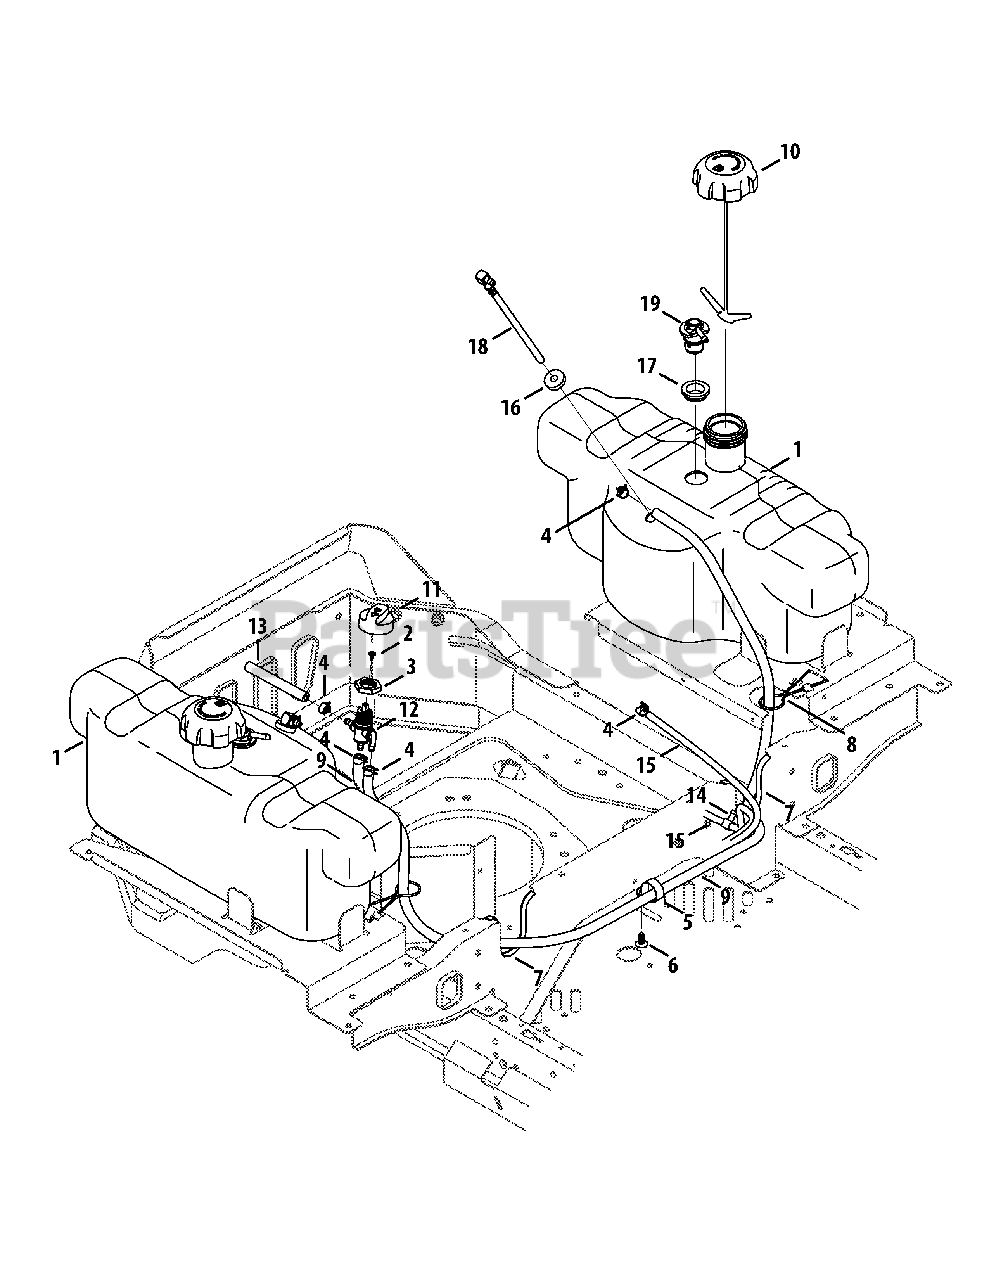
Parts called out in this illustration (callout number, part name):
1	Fuel Tank
2	Screw, M4-0.7 x 8mm
3	Nut, 3 Way Select
4	Hose Clamp, .490 Dia.
5	Hose Clamp, 1.0
6	Ratchet Clip, .250
7	Trim Strip
8	Tank Support Rod
9	Fuel Hose, Low Permeation, 1/4
10	Fuel Cap
11	Fuel Cap, 3 Way
12	Fuel Switch
13	Fuel Hose, Low Permeation, 1/4
14	Tee Fitting
16	Fuel Tank Bushing
17	Rubber Grommet
18	Fuel Pickup Fitting
19	Rollover Valve
